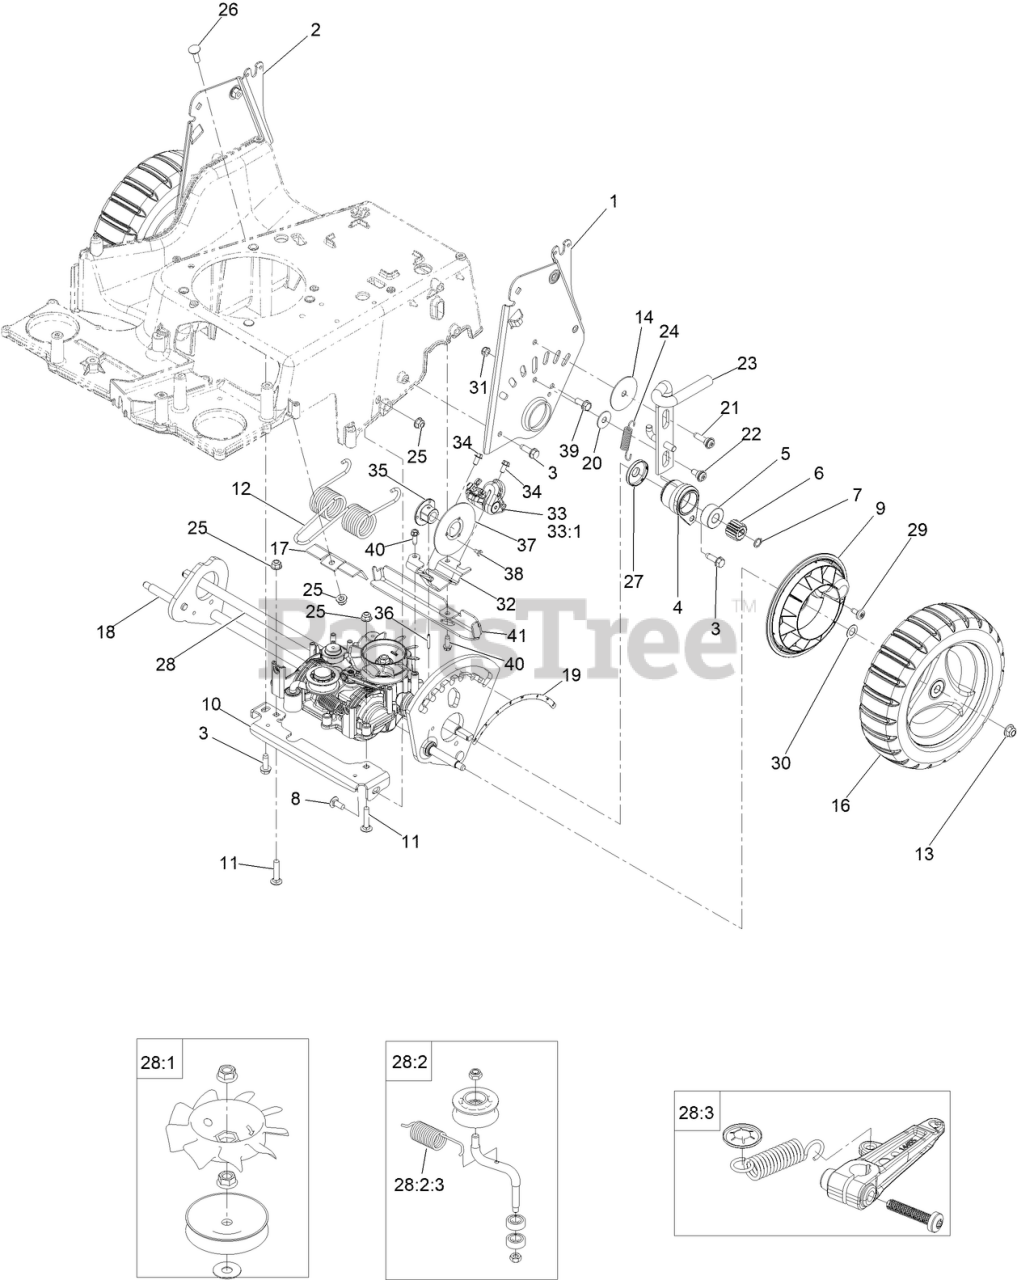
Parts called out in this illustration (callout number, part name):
1	HOC Plate Assembly
2	HOC Plate Assembly
3	SCREW-THD ROLL, HWH
4	Bearing Retainer ASM
5	BEARING-BALL, CUSTOM
6	GEAR-PINION, 15T
7	RING-RETAINING
8	SCREW-CARR
9	Cover-Wheel
10	Bracket-Transmission, Front
11	BOLT-CARR
12	SPRING-TORSION
13	NUT-HF, NI
14	WASHER-PLAIN
16	WHEEL ASM, 10.5 W/GEAR
17	BRACKET
18	REAR AXLE ASM
19	DECAL-HOC, REAR
21	SCREW-SHOULDER, BHTF
22	BOLT-SHOULDER
23	LOCK-HEIGHT, ADJ
24	Wheel ASM, 10.5 W/Gear
25	NUT-HF, NI
26	BOLT-CARR
27	COVER-BEARING
28	TRANSMISSION-MV702
28:1	Pulley & Fan Repair Kit
28:2	Idler Pulley Repair Kit
28:2:3	Spring-Tension, Belt
28:3	Clutch Lever Repair Kit
29	SCREW-SHOULDER
30	WASHER-PLAIN
31	NUT-LOCK, NI
32	Bracket-Mount, Brake
33	CALIPER-BRAKE, DISC
34	SCREW-HWH
35	Hub-Rotor
36	Pin-Roll
37	Disc-Rotor
38	SCREW-TORX PH THD ROLL
40	SCREW-HWHTF
41	Bracket-Support, Cable
